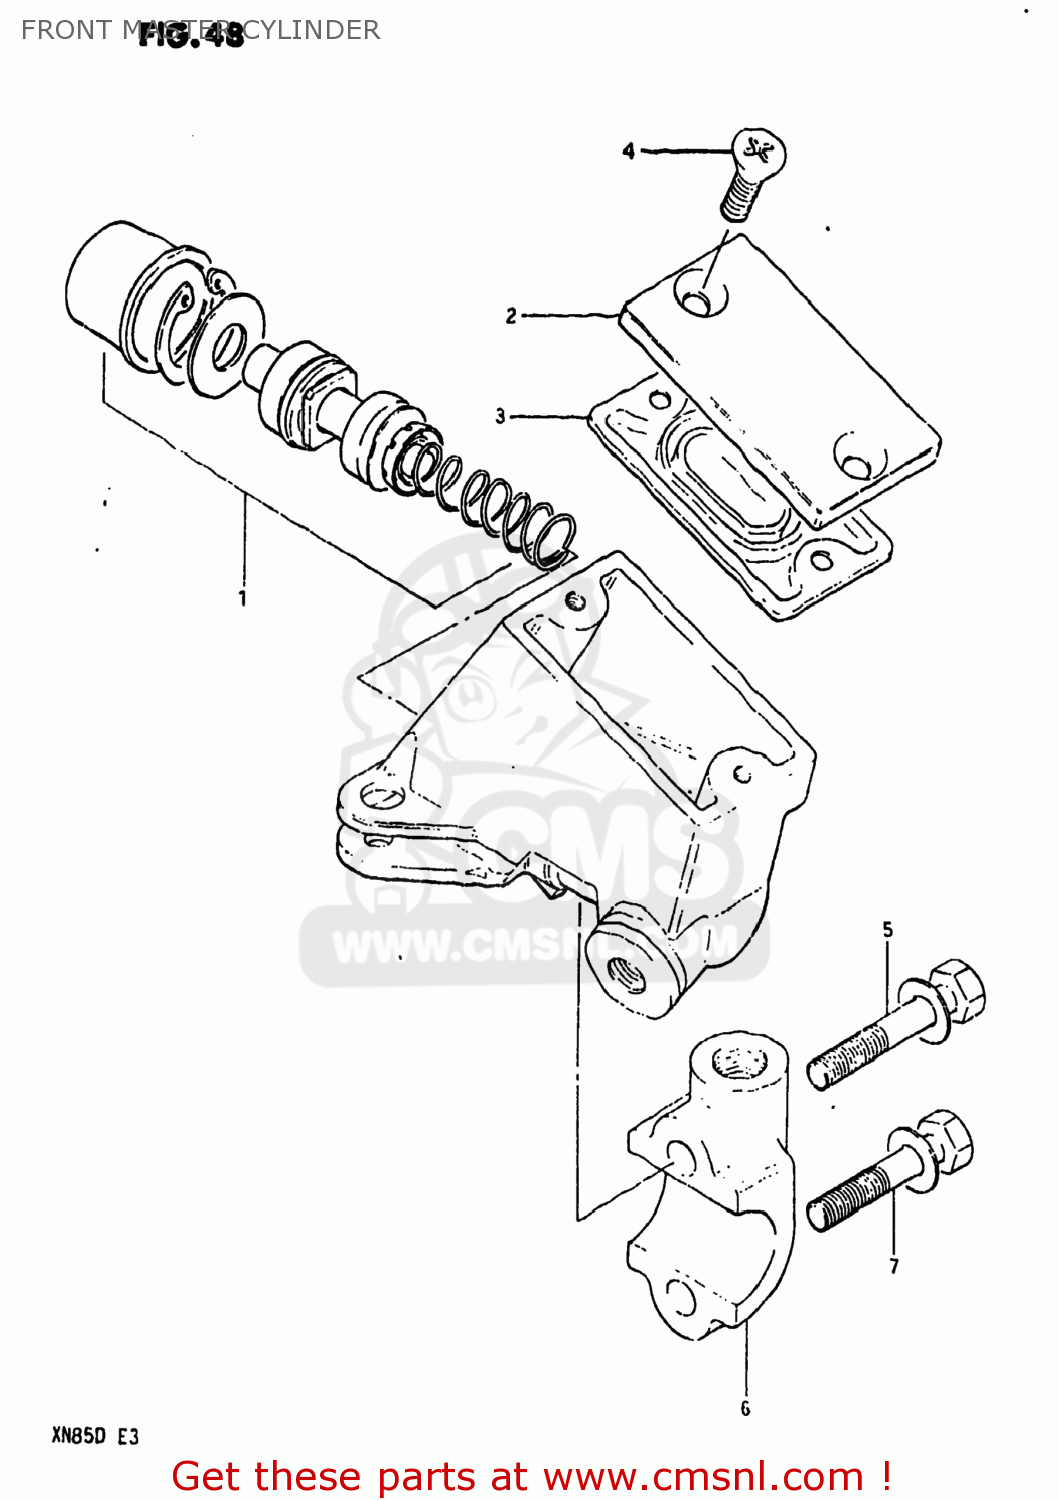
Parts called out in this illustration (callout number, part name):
1	PISTON & CUP SET
2	CAP,MASTER CYLINDER,REAR
3	DIAPHRAGM,MASTER CYLINDER
4	SCREW
5	BOLT,MASTER CYLINDER H
6	HOLDER
7	BOLT,MASTER CYLINDER H
